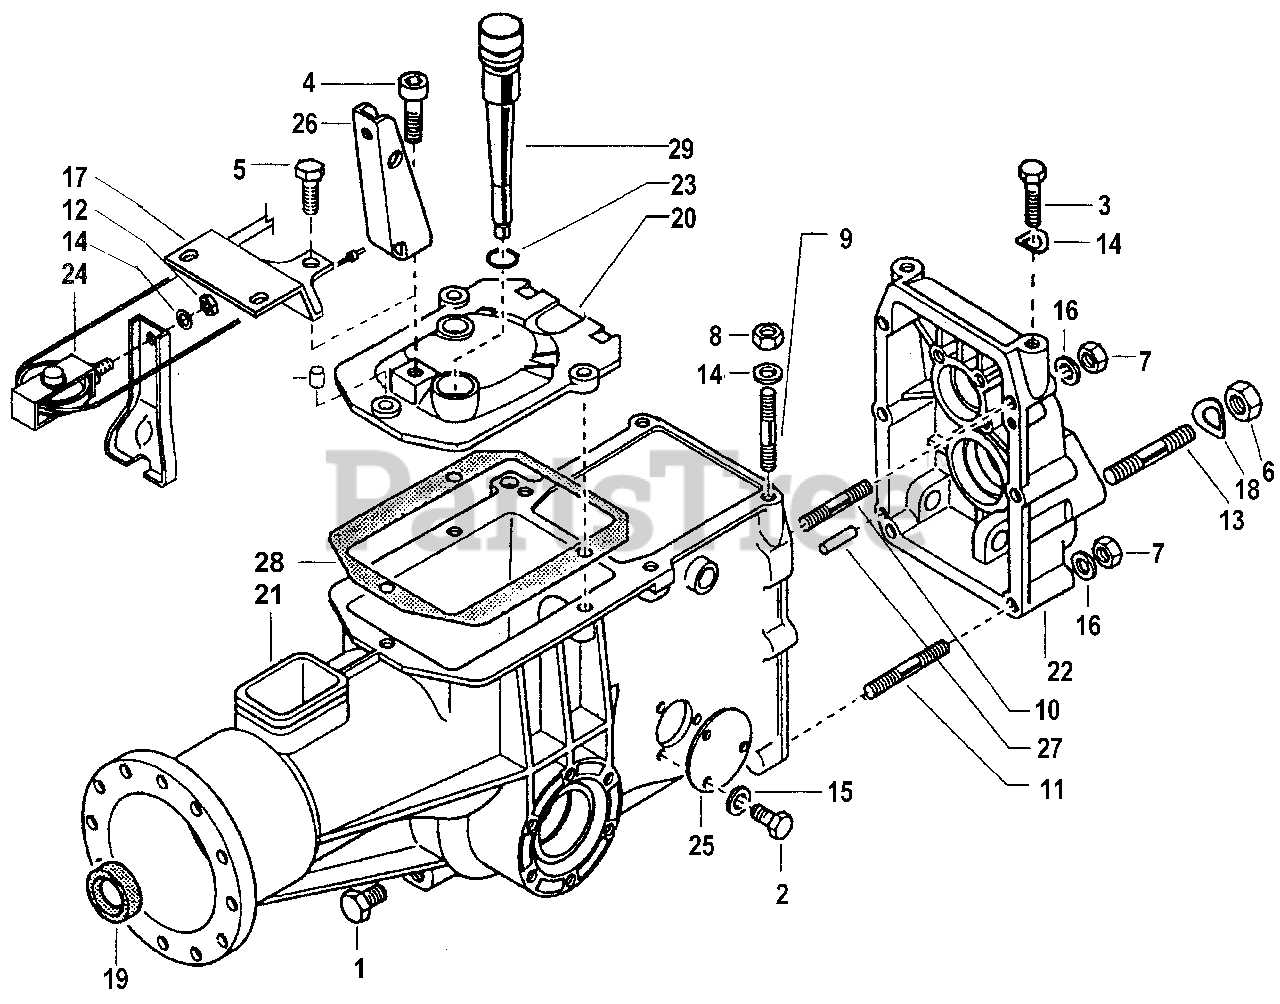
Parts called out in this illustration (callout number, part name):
2	SCREW M6X10
3	SCREW M8X20
4	SCREW M10X25
6	NUT, M12X1.25
7	NUT, SELF LOCKING M8
9	SUTDM8X38X14X20
10	STUD,M8X58X16X16
11	STUD,M8X68X16X16
12	STUD,M10X37X19X15
13	STUD,M12X1.25X12X52
14	SUPER WASHER
15	WASHER, LOCK 6.4
16	WASHER, LOCK 8.4
17	WASHER, LOCK 10.4
18	WASHER, LOCK 13.4
24	CLUTCH BRACKET
26	CLUTCH BRACKET
27	PARALLEL PIN
28	GASKET, COVER
